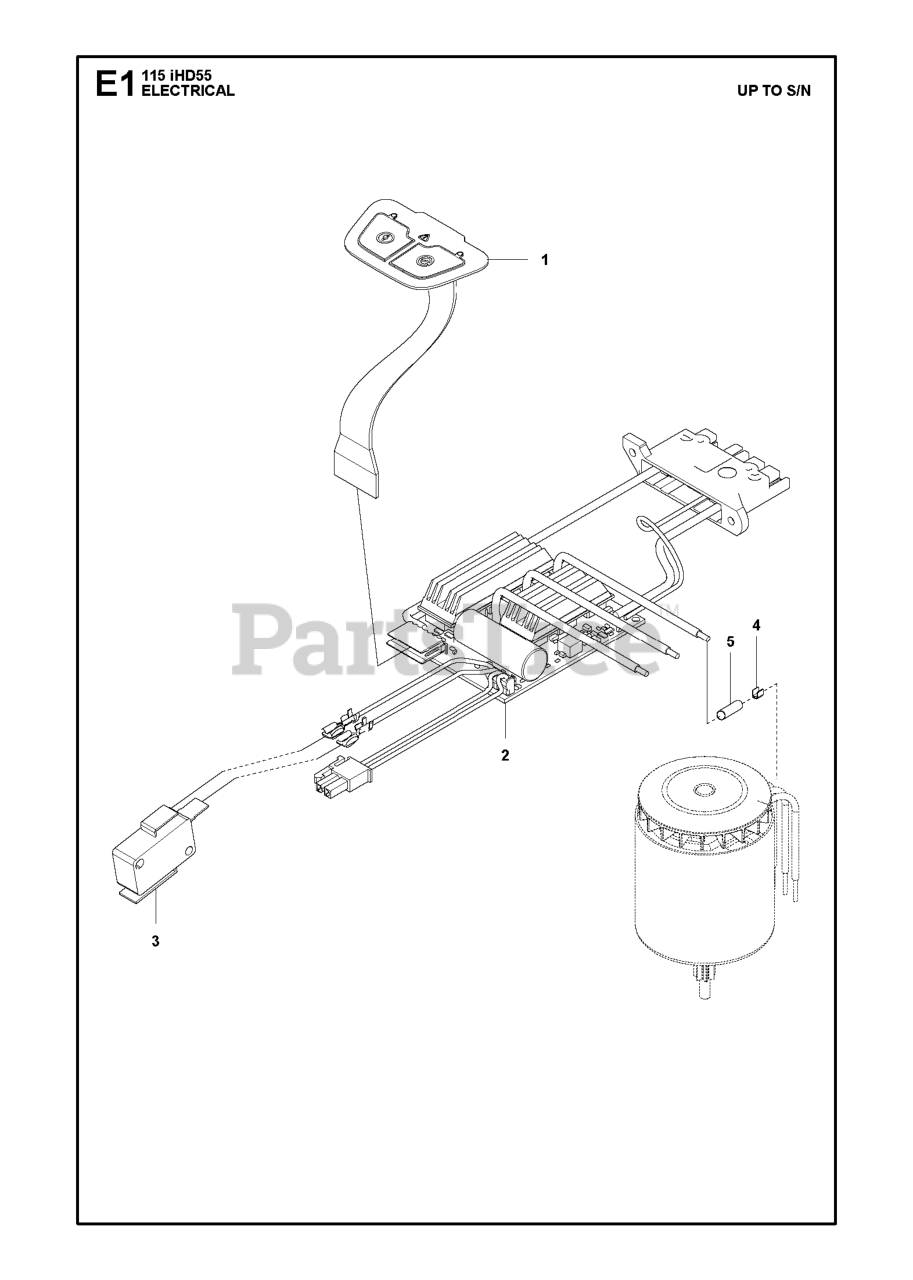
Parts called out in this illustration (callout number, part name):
1	KEYPAD HEDGE TRIMMER
2	CONTROL UNIT CONTROL UNIT BLDC
3	MICRO SWITCH
